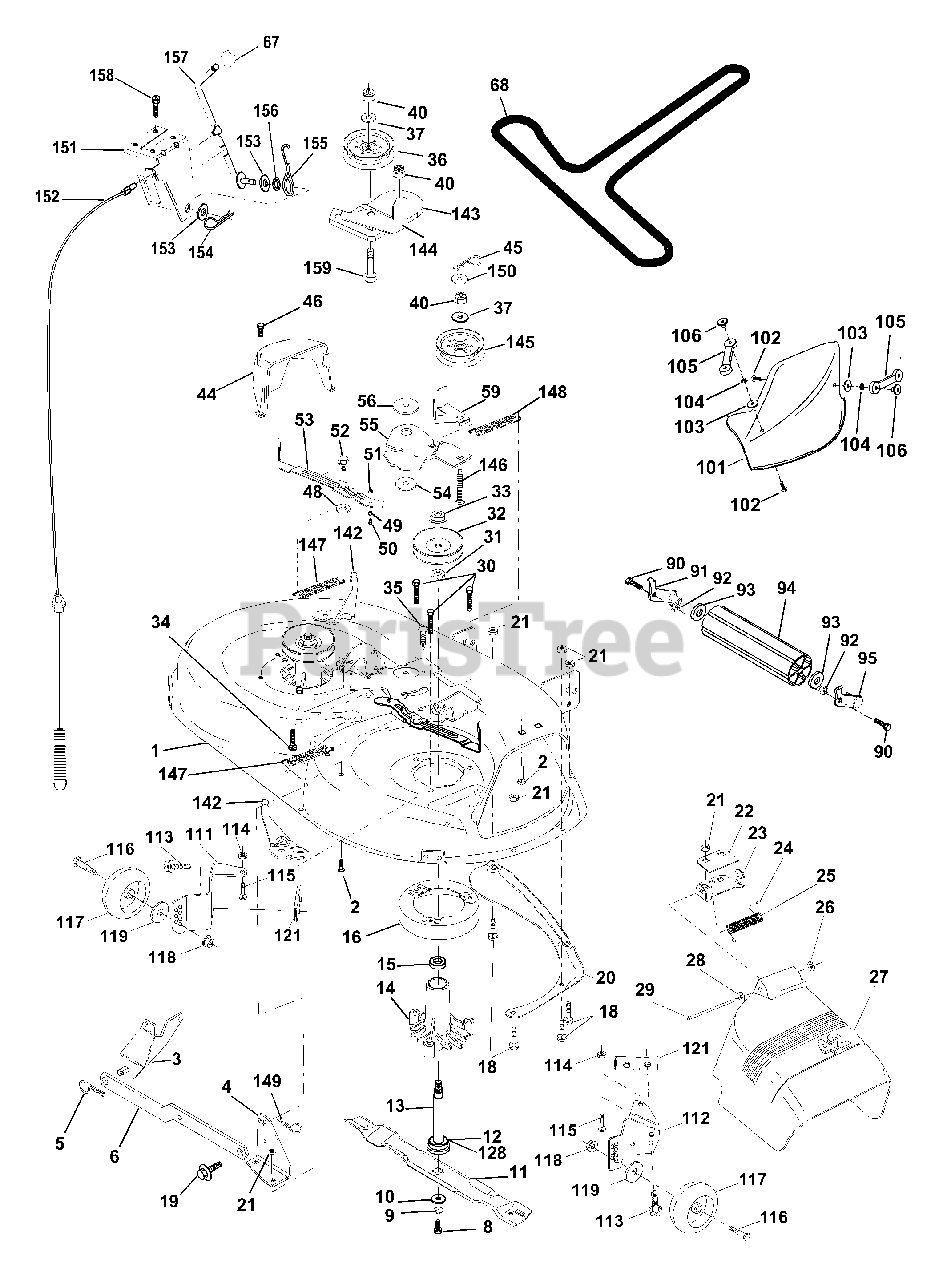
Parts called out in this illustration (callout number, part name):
1	Mower Deck Assembly, 42"
2	Bolt
3	Bracket Asm Fr. Sway Bar 3/42
4	Bracket Asm Deck 42" Sway Bar
5	Retainer Spring
6	Arm, Suspension, Rear
8	Bolt 3/8-24 x 25 Grade 8 patched
9	Washer, Lock
10	Washer,Hardened
11	Blade, Mulching 42"
11	Blade Mower 42" Hi-Lift
12	Bearing, Ball #6204
13	Shaft Assembly, Mandrel, Vented
14	Housing, Mandrel, Vented
15	Bearing, Ball, Mandrel
16	Stripper, Vented Mower Deck
18	Bolt, Carriage 5/16-18 x 5/8
19	Bolt, Shoulder
20	Baffle, Vortex
21	Nut
22	Stiffener Bracket
23	Bracket, Deflector Mower 42"
24	Cap, Sleeve 80 x 112 Blk Mower
25	Spring, Torsion, Deflector 2 52
26	Nut, Push Phos & Oil
27	Shield, Deflector 42" Blk
28	Washer 11/32 x 5/8 x 16 Gauge
29	Rod, Hinge 42" 6 75 W/G
30	Screw Thdrol Washer Head
31	Washer, Spacer Mower Vented
32	Pulley, Mandrel
33	Nut, Toplock 9/16
34	Bolt
35	Fastener, Christmas Tree
36	Pulley, Idler, Flat
37	Washer 13/32 x 13/16 x 16 Gauge
40	Nut
44	Guard, Mandrel, LH
45	Retainer
46	Screw, Thdrol 1/4-20 x 5/8 T
48	Washer,Hardened
49	Roller Assembly, Cam Follower
50	Bolt, Shoulder #10-24 Grade 5
51	Locknut
52	Bolt, Shoulder 5/16-18 UNC
53	Arm Assembly, Pad, Brake
54	Washer,Hardened
55	Arm, Idler
56	Spacer, Retainer
59	Guard TUV Idler
67	Knob
68	V-Belt, 42" Mower
90	Bolt Fin Hex 3/8-16 Unc x 1
91	Bracket Asm. Noseroller LH
92	Nut, Lock, Hex W/Ins 3/8-16 UNC
93	Washer 17/32 x 7/8 x 16 Ga.
94	Roller, Nose
95	Bracket Asm. Noseroller RH
101	Mulcher Cover
102	Screw
103	Washer, Flat
104	Washer, Lock
105	Latch Assembly
106	Nut, Weld
111	Bracket, Gauge, Wheel LH
112	Bracket, Gauge, Wheel RH
113	Screw 5/16 - 18 x 3/4
114	Nut, Keps 5/16 - 18 UNC
115	Bolt, Carriage 5/16-18 x 1/2
116	Bolt, Shoulder
117	Wheel, Gauge
118	Nut Centerlock 3/8-16
119	Washer 3/8 x 7/8 x 14 Ga.
121	Bracket, Extruded
128	Washer, Felt
142	Arm Spring Brake Mower
143	Bracket Arm Idler 42"
144	Keeper Belt 42" Clutch Cable
145	Pulley Idler Flat
146	Bolt Carriage Idler
147	Spring Extension
148	Spring Return Idler
149	Retainer Spring Yellow
150	Washer 9/32 x 3/4 x 16 Ga.
151	Bracket Clutch Cable
152	Clutch Cable 42"
153	Washer Flat 3/8" Type B
154	Spring Retainer
155	Spring Retention LVR CLTCH CAB
156	Spacer Clutch Cable
157	Rod Clutch Cable 3/8"
158	Screw Hex Thd Cut 1/4-20 x 5/8
159	Bolt Rdhd Sqn 3/8-16 UNC x 1-3/4
